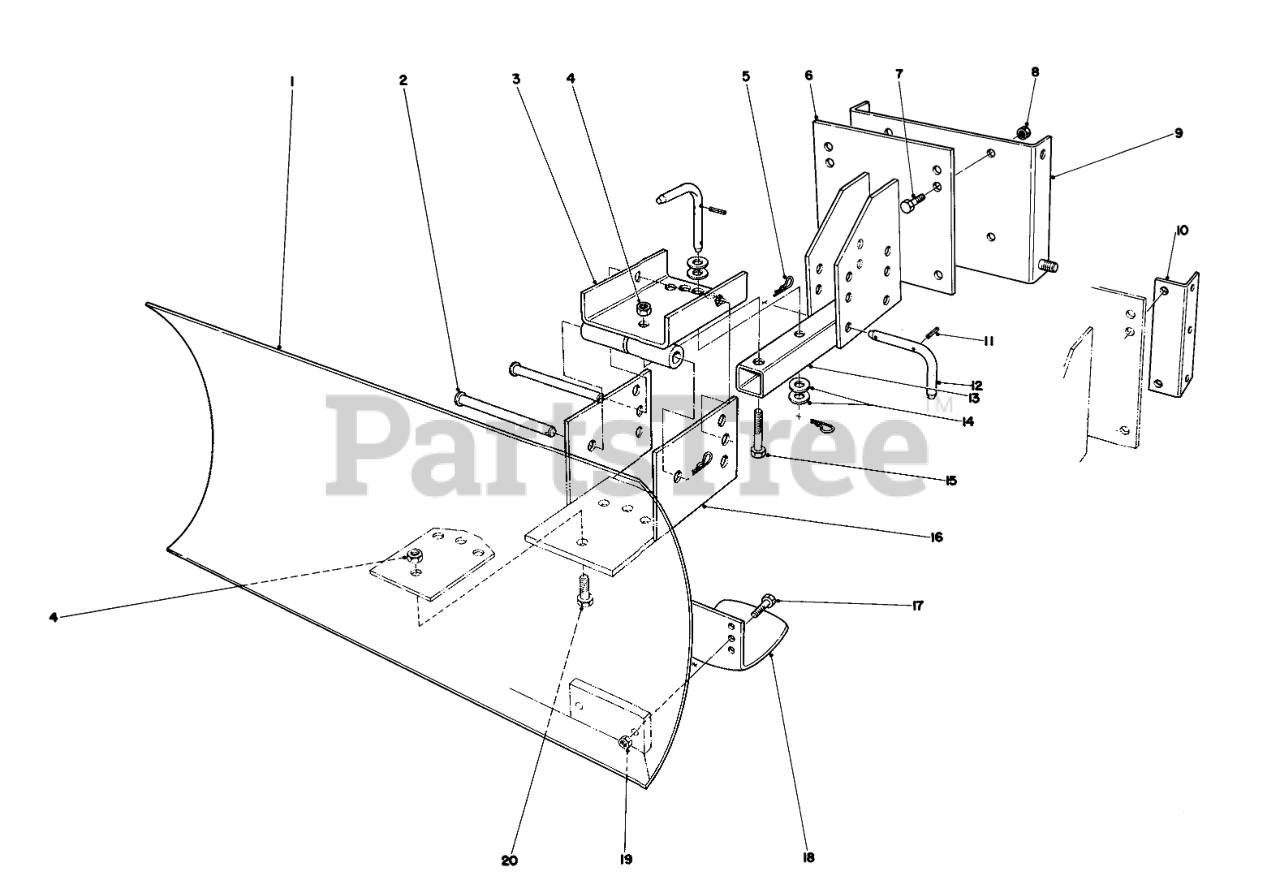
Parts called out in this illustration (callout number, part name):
1	Blade
2	PIN-CLEVIS
3	Swivel Bracket
4	PART CAT OPC
5	PIN-HAIR
6	70 Mounting Plate
7	SCREW-HH
8	PART CAT OPC
9	Mounting Plate (Used with 826 & 1132 Units only)
10	Mounting Rail (used with 421 units only)
11	PIN-SPRING
12	Pivot Pin (Incl.Ref. #11)
13	Blade Tongue
14	WASHER-FLAT
15	SCREW-HH
16	Blade Adjustment
17	SCREW-HH
19	NUT-LOCK, CONE
20	SCREW-HH
